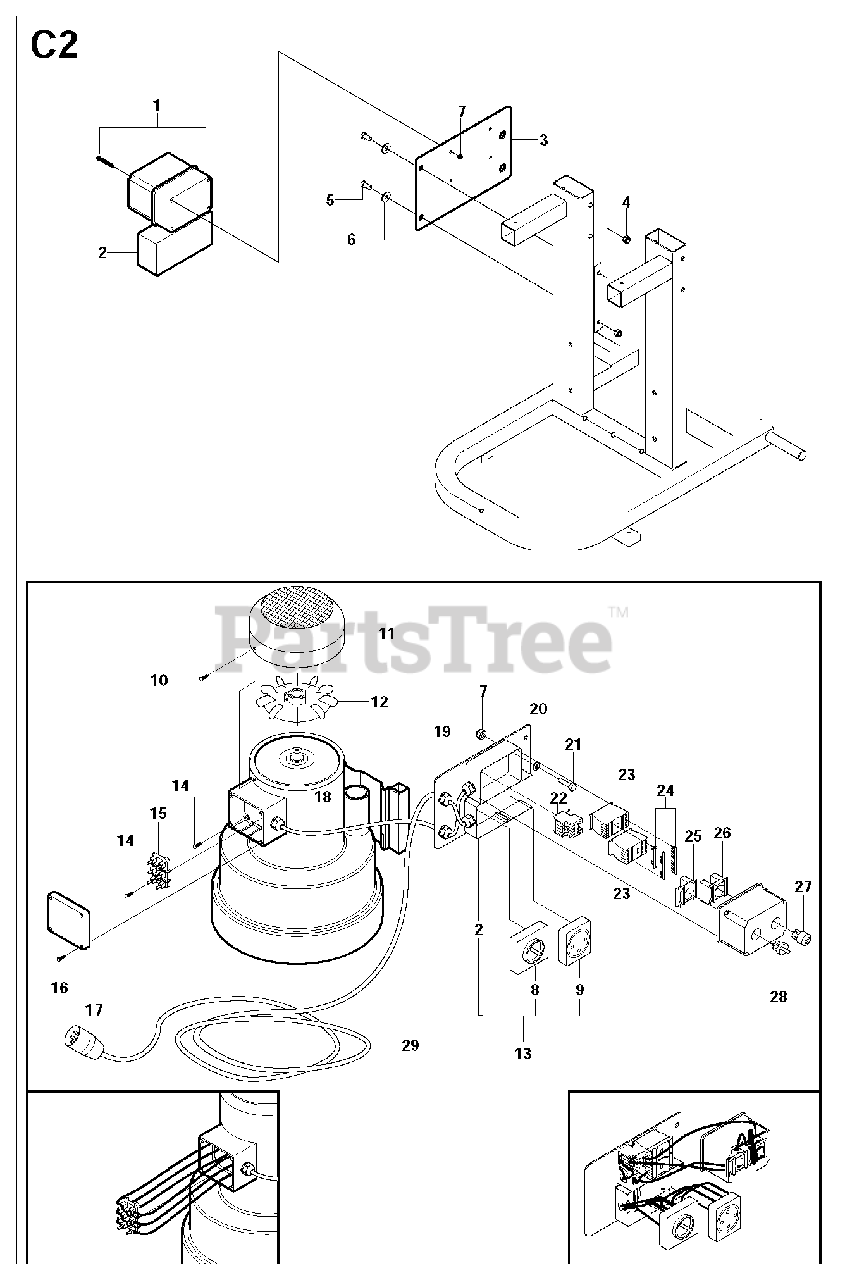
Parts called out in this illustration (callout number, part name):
9	HEXAGON LOCKING NUT
11	WASHER
12	HEXAGON LOCKING NUT
13	SCREW EHHMIncludes 2,8,9
20	WASHER
